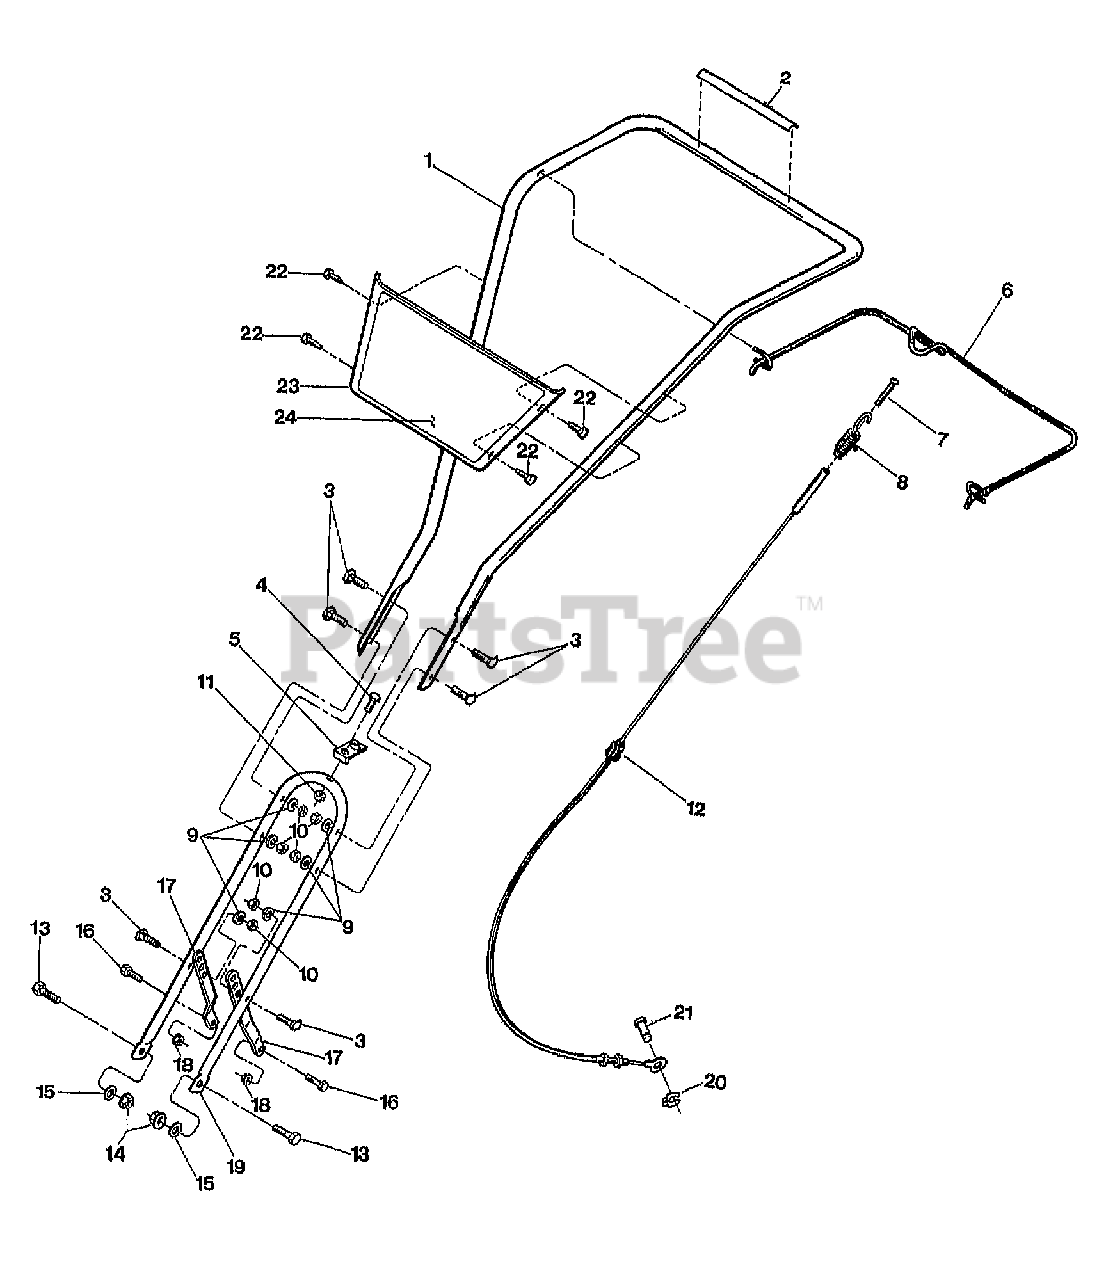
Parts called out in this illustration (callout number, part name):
1	HANDLEBAR-UPR W/DECAL
2	DECAL-55103
3	SCR-CUR.H.5/16X1 1/2
4	SCR-HH 1/4-20X1.25
5	TAB-CONDUIT MOUNT
6	BAIL-FWD. DRIVE PNT
7	SCR-SLOT.H.10-24X2
8	ASSM-SPRING CABLE
9	WASHER-LK .312 ZP
10	NUT-HEX 5/16-18 ZP
11	NUT-LK 1/4-20
12	ASSM-CONTROL CABLE
13	SCR-HH 3/8-16X.75 G5 ZP
14	NUT-LOCK 3/8-16 NYLON ZP
15	WASHER-FLAT 3/8 SAE
16	SCR-HHC 5/16-18X.75 GR 5 ZP
17	LINK-H/BAR PNT
18	NUT-H/LK 5/16-18
19	HANDLEBAR-LWR PNT
20	RING-KLIP .188 DIA
21	PIN-CLEVIS CABLE
22	SCR-HWH 1/4-20 X .5 STH
23	PANEL-55102 PNT
24	DECAL-GRAPHICS PANEL TUFFY (MODEL NAME & LOGO)
